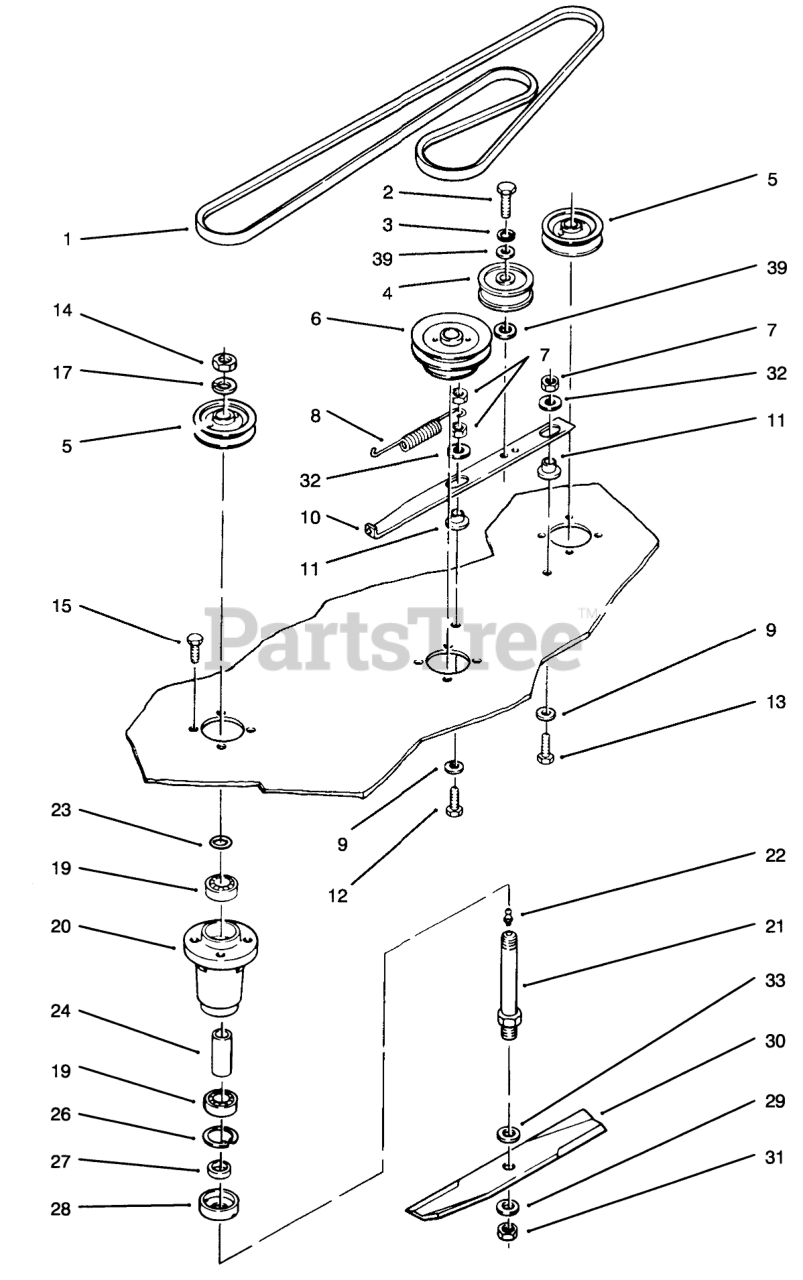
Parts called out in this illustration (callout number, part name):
1	V-BELT
2	SCREW-HH
3	WASHER-LOCK
5	PULLEY-BLADE, DRIVE
6	PULLEY-MOWER, 48IN
7	NUT-LOCK, NI
8	SPRING-EXTENSION
9	WASHER
10	BAR-IDLER SUPPORT
11	SPACER-BUSHING
12	SCREW-HH
13	SCREW-HH
14	NUT-JAM
17	WASHER-LOCK
19	BEARING-BALL
20	HOUSING-SPINDLE
21	SHAFT-SPINDLE
22	FITTING-GREASE
23	O RING
26	RING-RETAINING
27	SPACER-BLADE
29	WASHER-FLAT
31	NUT-JAM
32	WASHER
39	WASHER-FLAT
